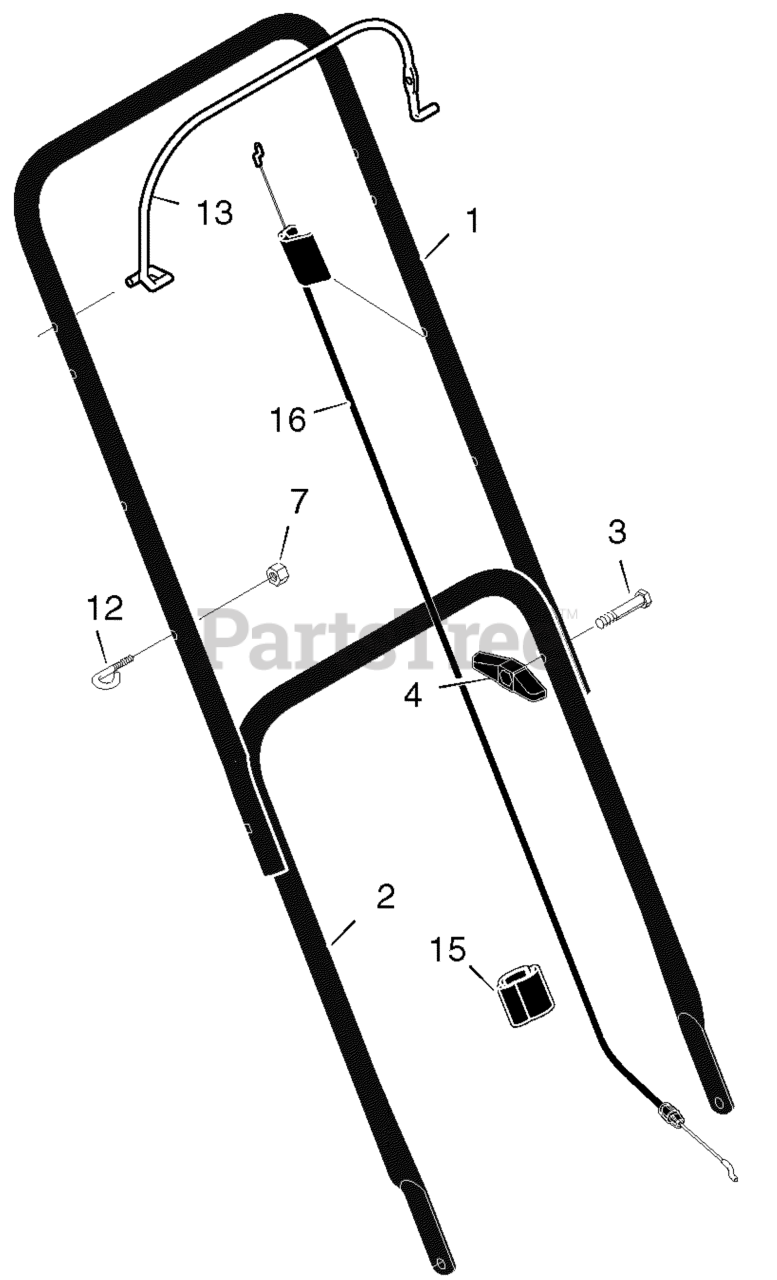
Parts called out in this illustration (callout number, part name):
1	Handle, Upper (Black)
2	Handle, Lower (Black)
4	Knob, Plastic
7	Locknut
12	Guide, Rope
13	Engine Stop Lever
15	Fastener, Cable
16	Engine Stop Cable
